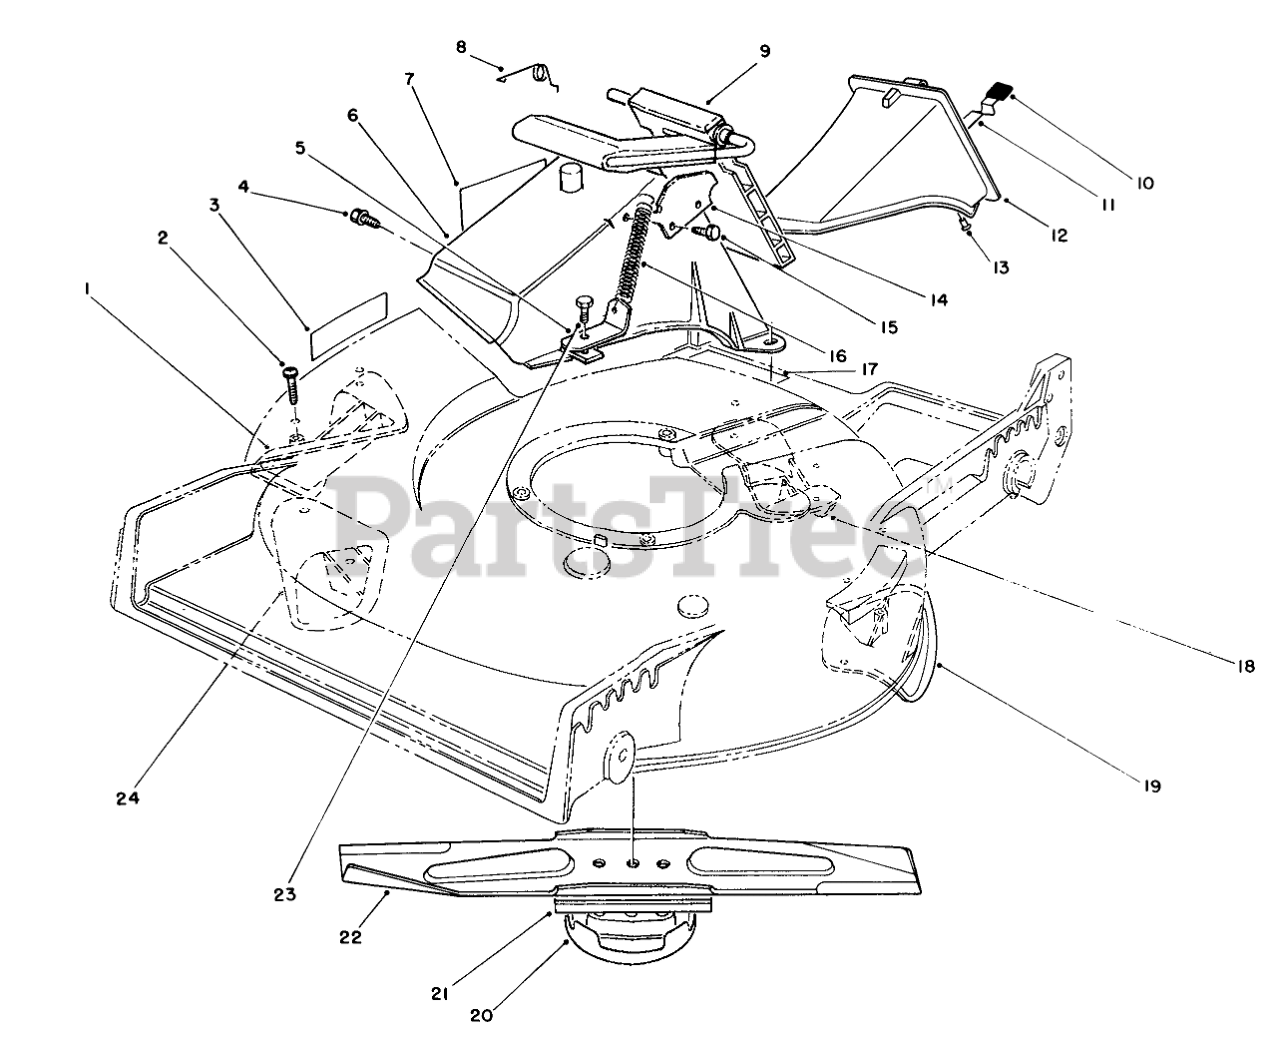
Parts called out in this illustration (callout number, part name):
1	KICKER
2	SCREW-PPH
3	DECAL - CAUTION
4	SCREW AND WASHER ASM
5	Bracket-Spring
6	TUNNEL-DISCHARGE
7	DECAL - DANGER
8	RETAINER-DOOR
9	DOOR ASSEMBLY
10	GRIP-LATCH
11	LATCH-PLUG, DISCHARGE
12	Plug Assembly (Incl. Ref. #10, 11 & 13)
13	RIVET-HEAD, FLAT
14	DOOR LATCH PLATE
15	SCREW-PLASTITE
16	SPRING-DOOR
17	Decal-Caution
18	KICKER
19	KICKER
20	CUP-SCALP, ANTI
21	Stiffener
22	Blade
23	SCREW-HWH
24	KICKER
